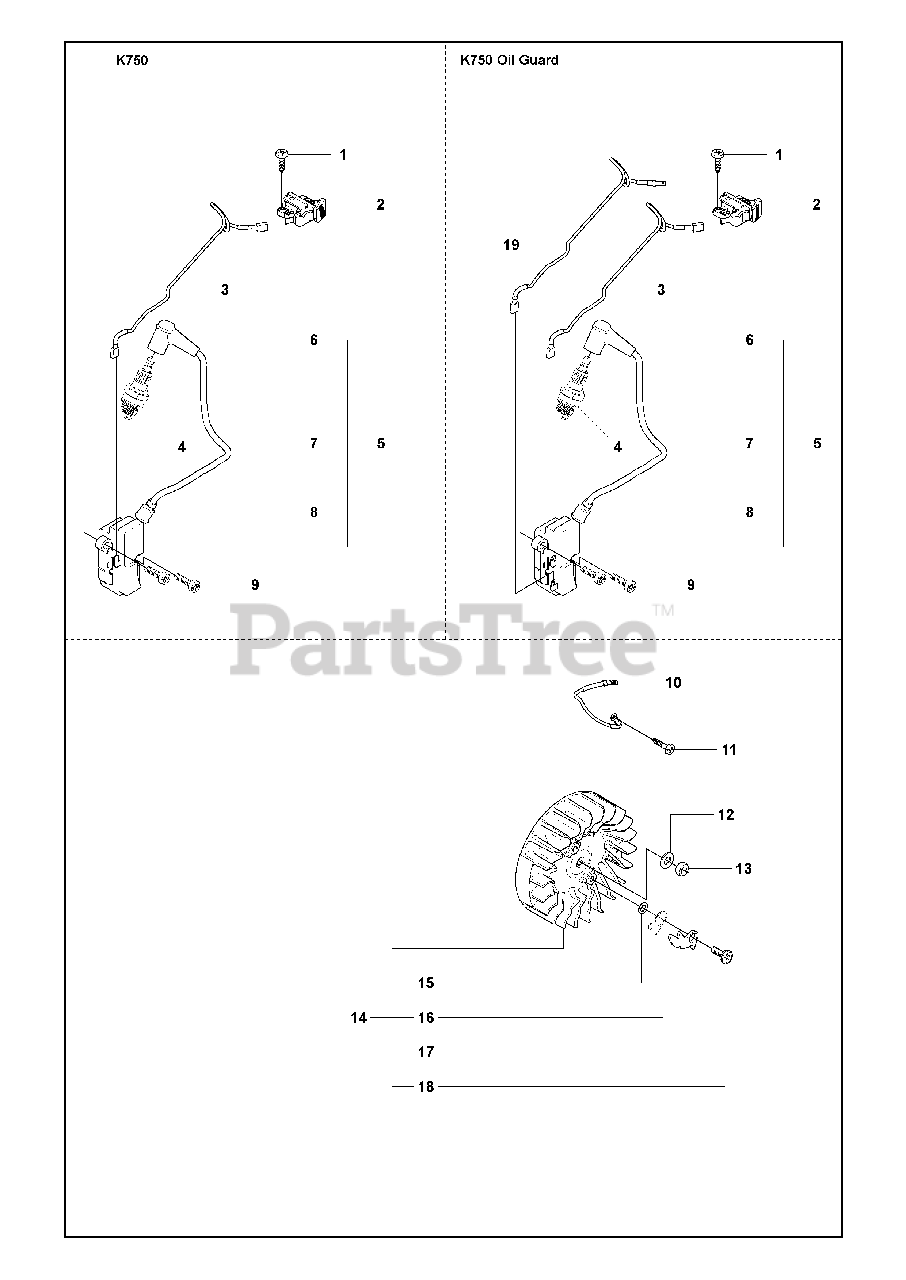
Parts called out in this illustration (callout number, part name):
2	STOP SWITCH
3	CABLE
4	SPARK PLUG
5	IGNITION MODULE
6	SPARK PLUG CAP
7	IGNITION CABLE
8	ISOLERHATT
12	WASHER STEEL
14	FLYWHEEL
15	WASHER STEEL
19	CABLE
